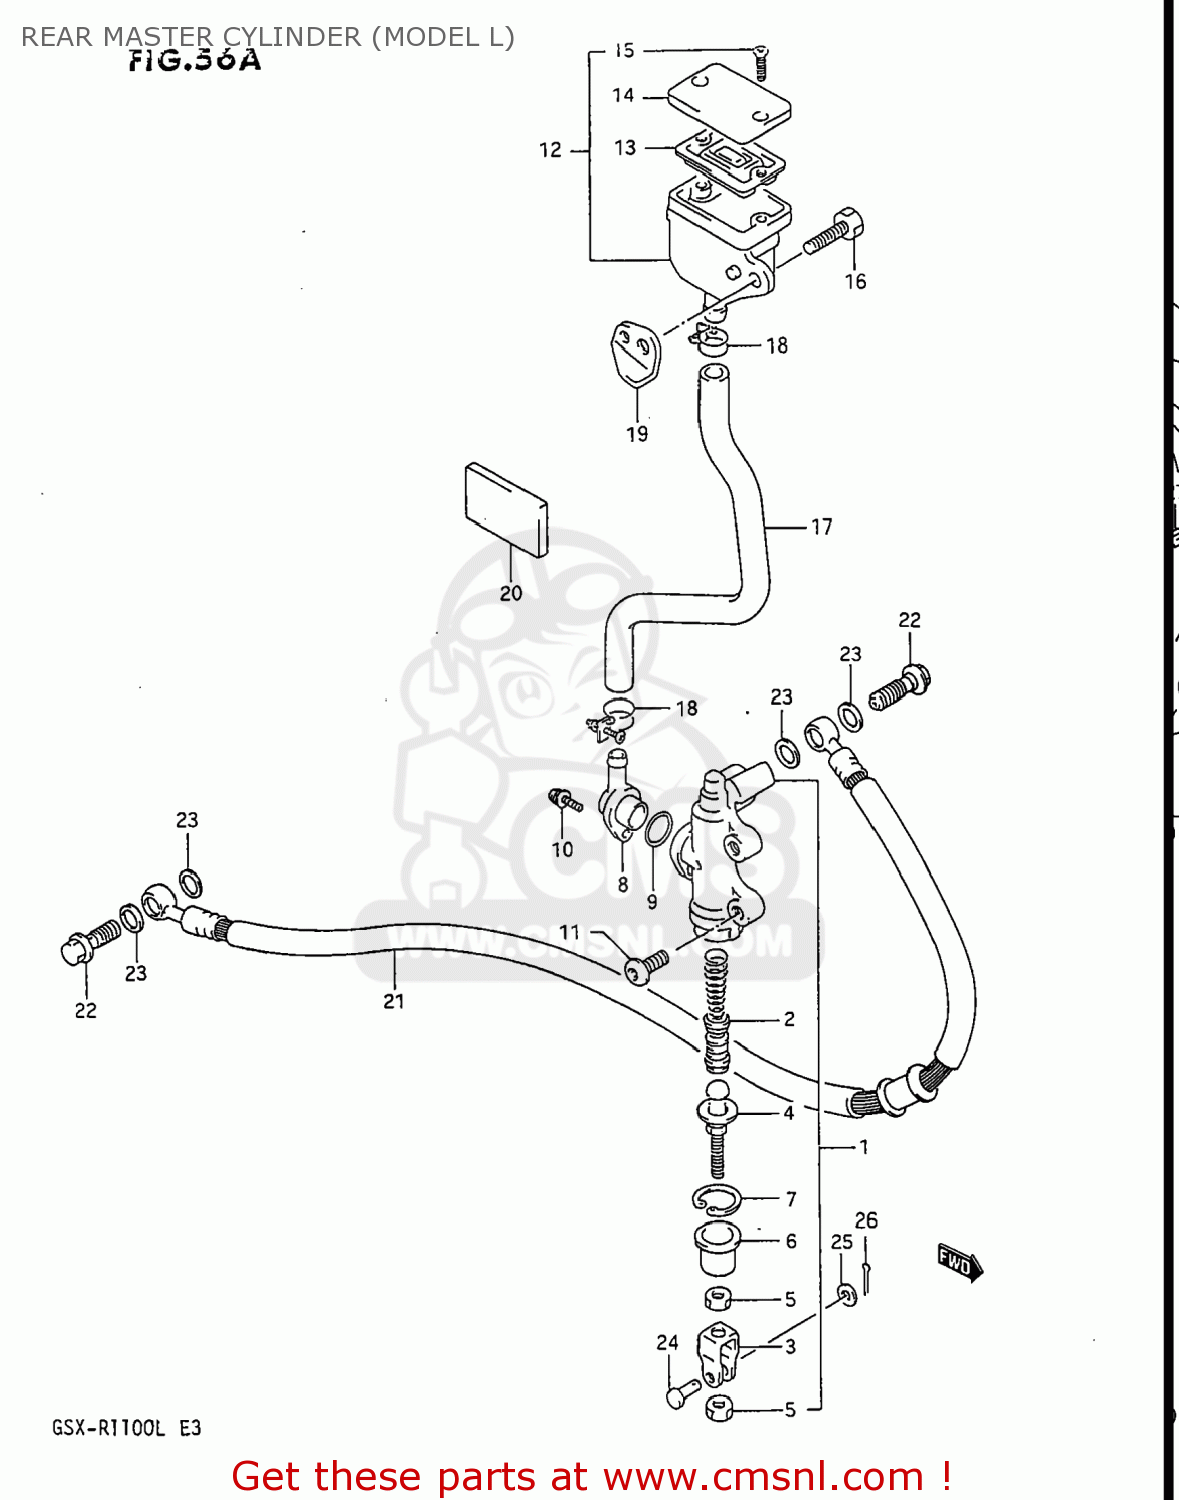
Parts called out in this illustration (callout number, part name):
1	CYLINDER ASSY,RR MASTER
2	PISTON/CUP SET
3	YOKE
4	ROD,PUSH
5	NUT
6	BOOT
7	CIRCLIP
8	CONNECTOR
9	O RING
10	SCREW
11	SCREW(8X22)
12	TANK ASSEMBLY,RESERVOIR
13	DIAPHRAGM
14	CAP
15	SCREW
16	BOLT
17	HOSE,RESERVOIR TANK
18	CLAMP
19	BRACKET,RESERVOIR TANK RR
20	CUSHION,PANEL
21	HOSE,REAR BRAKE
22	BOLT UNION
23	WASHER(10X15X1.5)
24	PIN
25	WASHER
26	PIN
